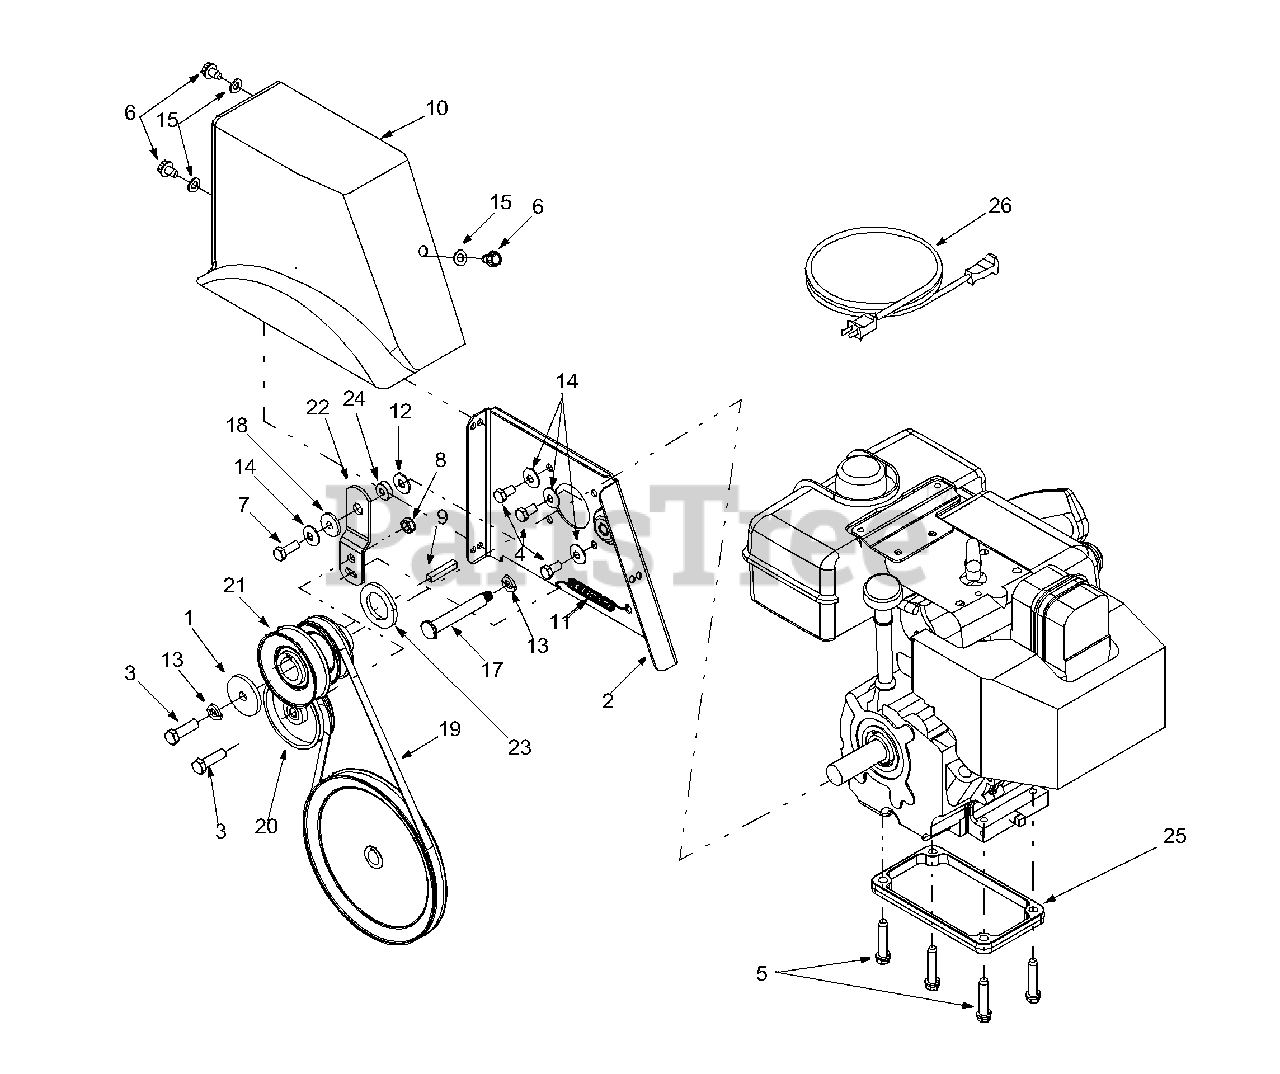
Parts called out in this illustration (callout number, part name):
4	Hex Screw 5/16-24 x .625"
5	Self-tapping Sems Screw
6	TT Screw 5/16-18 x 0.5"
7	Hex Lock Screw 5/16-24 x 1.25"
10	Belt Cover
11	Extension Spring
12	5/16 Washer
13	Lock Washer
14	Beleville Washer
15	Flat Washer
17	Shoulder Screw
18	Shoulder Spacer
19	V-Belt
20	Flat Idler
21	Double Pulley
22	Idler Bracket
24	Spacer, .33 x 1.0 x .36
26	Extension Cord, 110V, 3-prong
